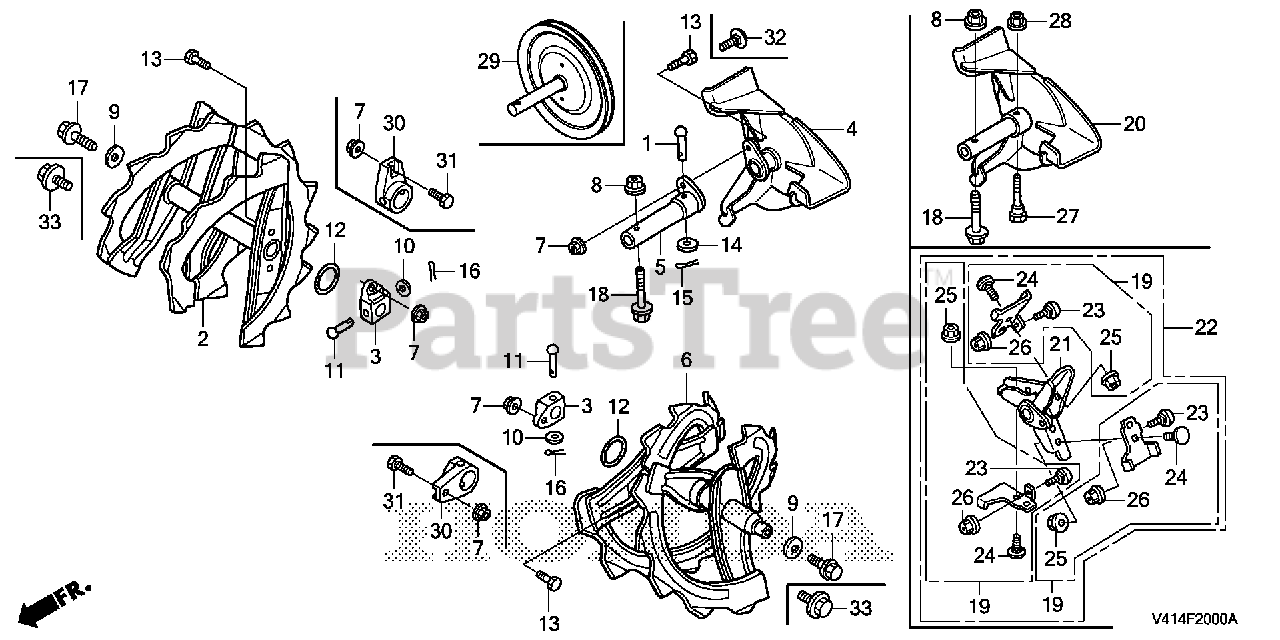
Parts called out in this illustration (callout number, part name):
1	PIN C, PILLION STEP
2	AUGER, R. (COO)
3	BOSS, LOCK BOLT
4	BLOWER
5	PIPE, JOINT
6	AUGER, L. (COO)
7	NUT, SELF-LOCK (6MM)
8	NUT, FLANGE (M8X1.25) (SELF-LOCK)
9	WASHER (23X8.3X3.2)
10	WASHER, PLAIN (7MM)
11	PIN (7X40)
12	O-RING (19.8X1.9) (ARAI)
13	BOLT, HEX. (6X18)
14	WASHER, PLAIN (6MM)
15	PIN, SPLIT (2.0X22)
15	PIN, SPLIT (2.0X35)
16	PIN, SPLIT (3.0X25)
16	PIN, SPLIT (3.0X45)
17	BOLT, FLANGE (8X16)
18	BOLT, FLANGE (8X35)
27	BOLT, LOCK
